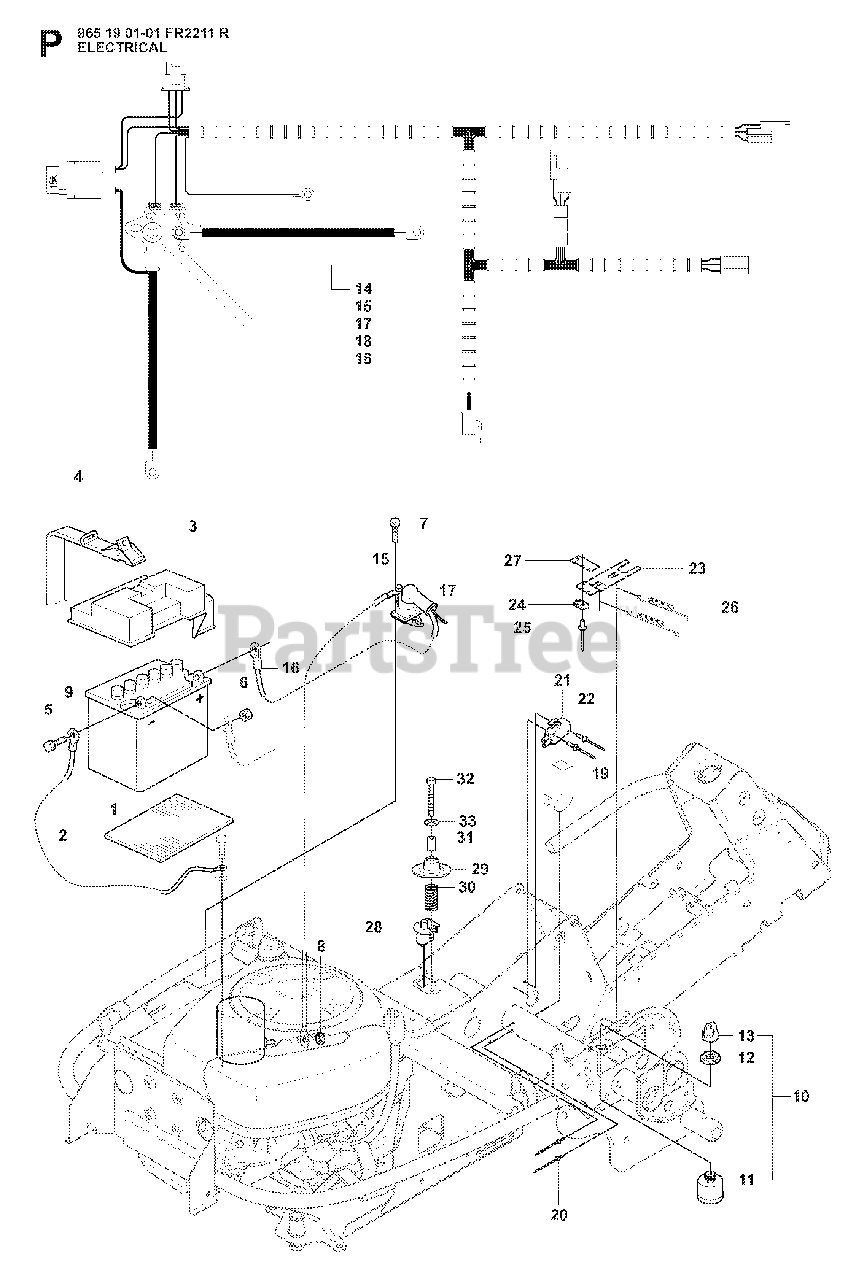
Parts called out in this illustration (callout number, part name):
1	BATTERY - DRY
10	IGNITION SWITCH
11	IGNITION SWITCH
13	IGNITION KEY
21	%BRAKER
24	%BRAKER
26	SPRING
31	SPACER TUBE
32	SCREW
33	WASHER BRB 8.4X17
